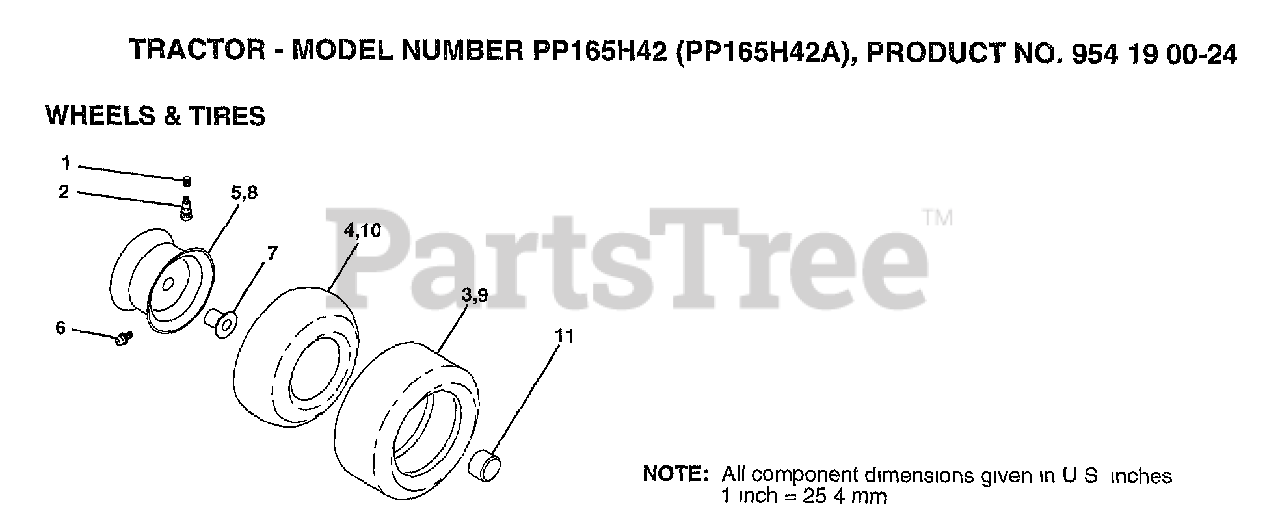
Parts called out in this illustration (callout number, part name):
1	VALVE CAP
2	VALVE STEM LT
4	TUBE.5.3/4.5/6
5	"RIM,FRT T"
6	FITTING LT
7	"FLANGE, BEARING"
8	"RIM 8"""
10	TUBE.18X9.5-8
11	HUB CAP
